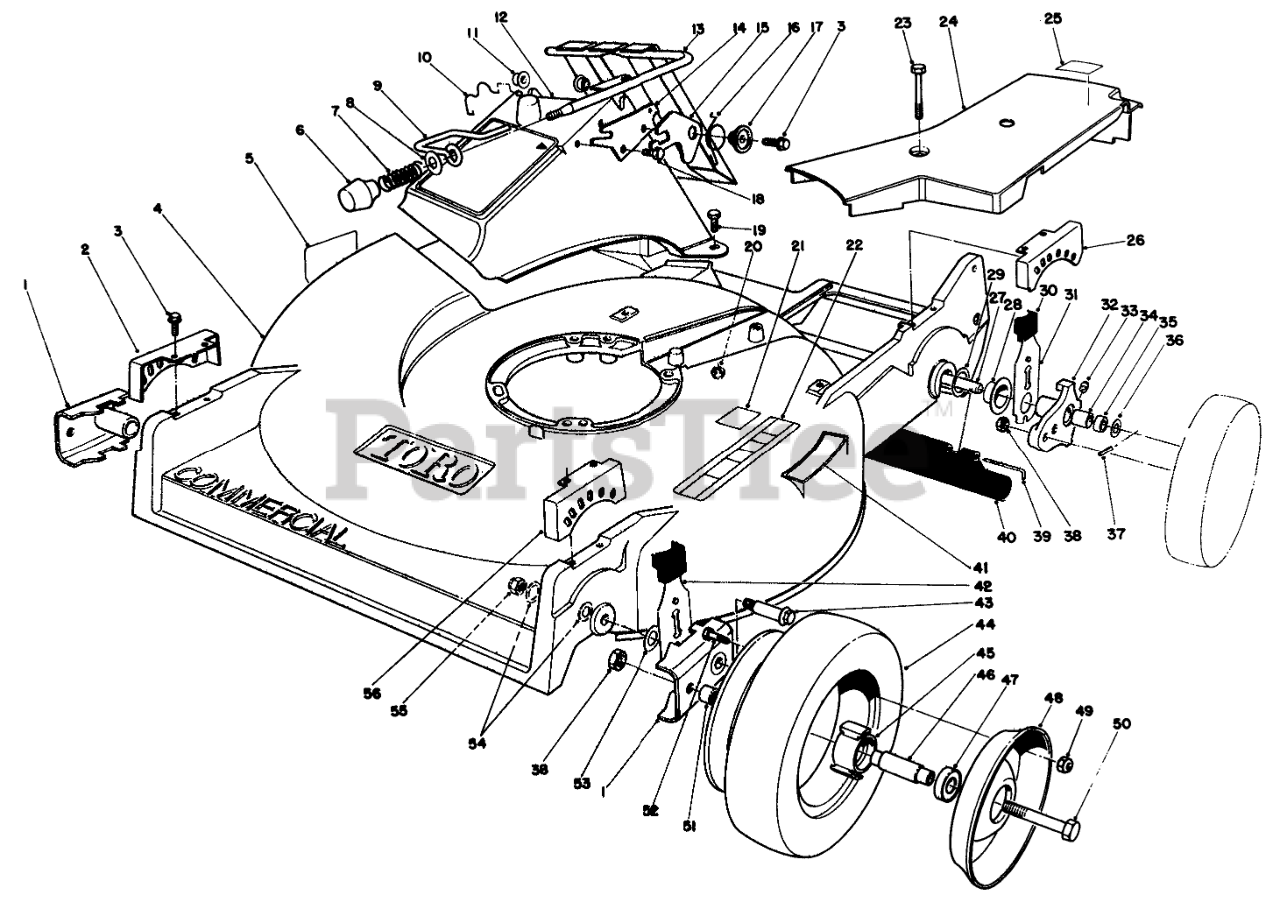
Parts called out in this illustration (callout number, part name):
1	ARM-PIVOT, FRONT
2	QUADRANT-FRONT, RH
3	SCREW-HWHTF
4	Housing-Commercial (Incl. Ref. #5, 21-22 & 41)
5	DECAL-DANGER
7	COMPRESSION SPRING
8	WASHER-FLAT
9	DOOR LATCH
10	DOOR RETAINER
11	BUSHING-NYLON
12	DISCHARGE CHUTE B
13	DOOR & HANDLE WA
14	DOOR LATCH PLATE
15	SAFETY LATCH
16	TORSION SPRING
17	DOOR SPACER
18	SCREW-HWH
19	SCREW-HH
20	NUT-LOCK, NI
21	Decal-Safety Standard
22	DECAL-INSTRUCTION, SAFETY
23	SCREW-HHFTF
24	COVER-BELT
25	LABEL-GREASE, HP
26	QUADRANT-REAR, LH
27	SHAFT-AXLE, REAR
28	CAP-END
29	WASHER
30	KNOB-ARM
31	REAR SPRING ARM ASM
32	Pivot Arm (Incl. Ref. 33-35)
33	FITTING-GREASE
34	BUSHING
35	BUSHING
36	WASHER-PLAIN
37	PIN-SPIROL
38	NUT-LOCK, CONE
39	ROD-SHIELD
40	SHIELD-TRAILING
41	STEP PAD DECAL
42	FRONT SPRING ARM ASM
43	WHEEL BOLT
45	HUB-BEARING
46	SPACER-BEARING
47	BEARING-WHEEL
48	Wheel-Half
49	NUT-LOCK, NI
50	SCREW-HH
51	SPACER-WHEEL
52	SCREW-HH
53	WASHER-THRUST
54	WASHER
55	Nut
56	QUADRANT-FRONT, LH
